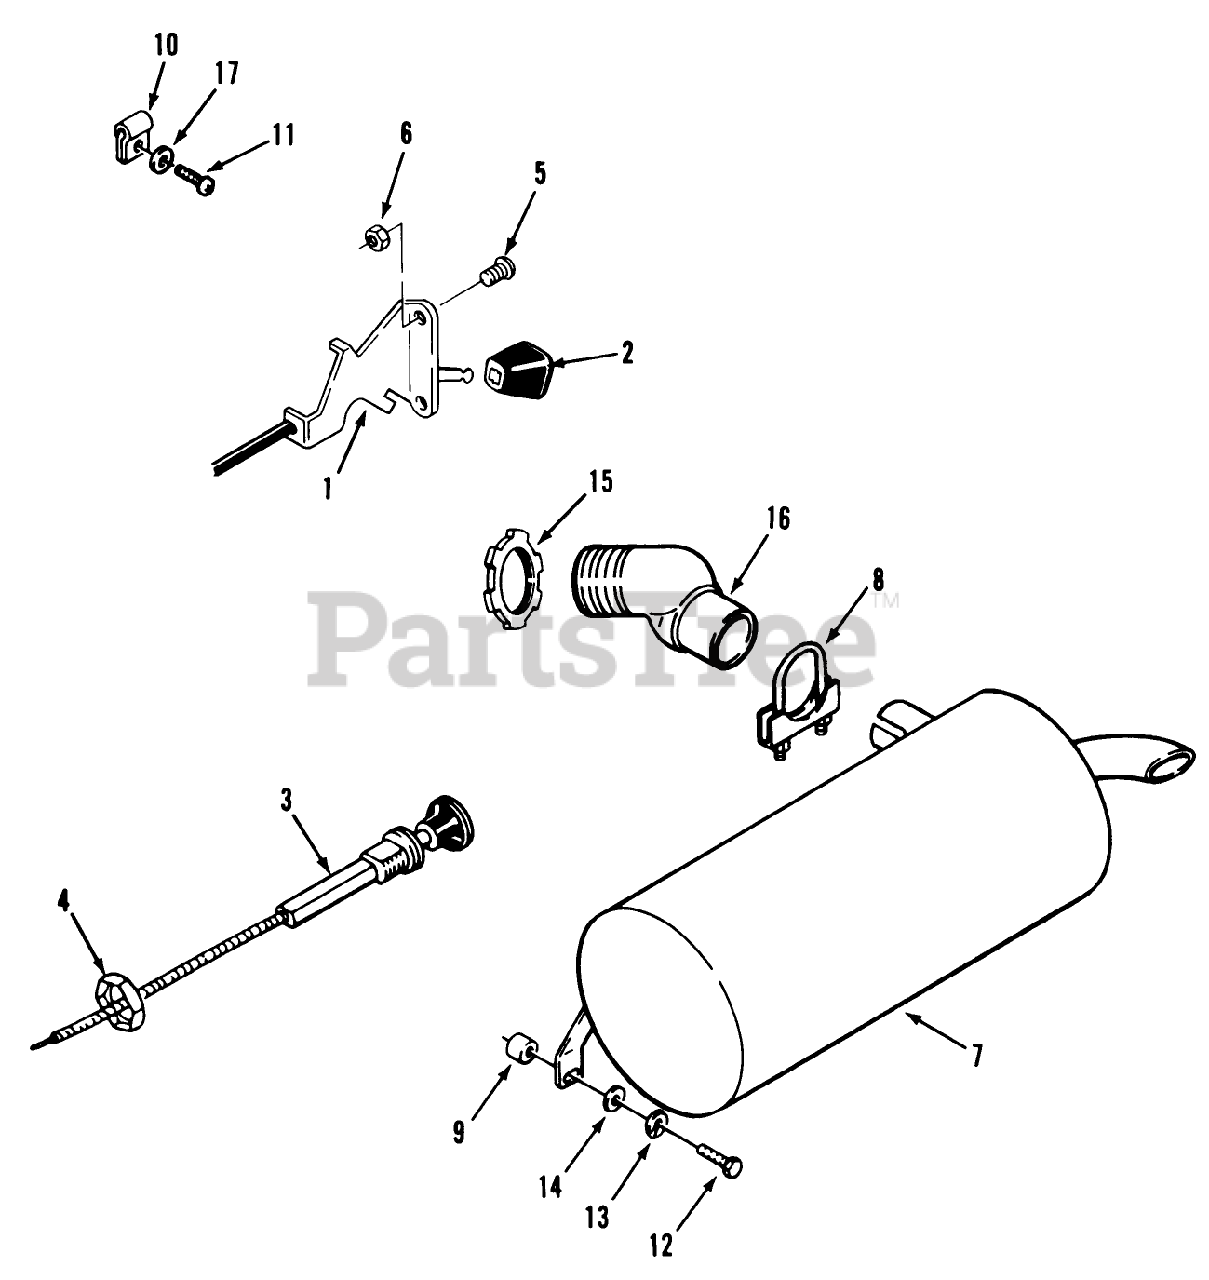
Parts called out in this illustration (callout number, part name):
1	CONTROL-THROTTLE
3	CONTROL CHOKE
4	NUT-HEX PALNUT
9	SPACER
10	KOHLER 48-154-01
11	KOHLER X-67-83
12	SCREW-HH
13	WASHER-LOCK
14	WASHER-FLAT
15	KOHLER AC-1536
16	KOHLER47-054-01
17	KOHLER X-25-72
